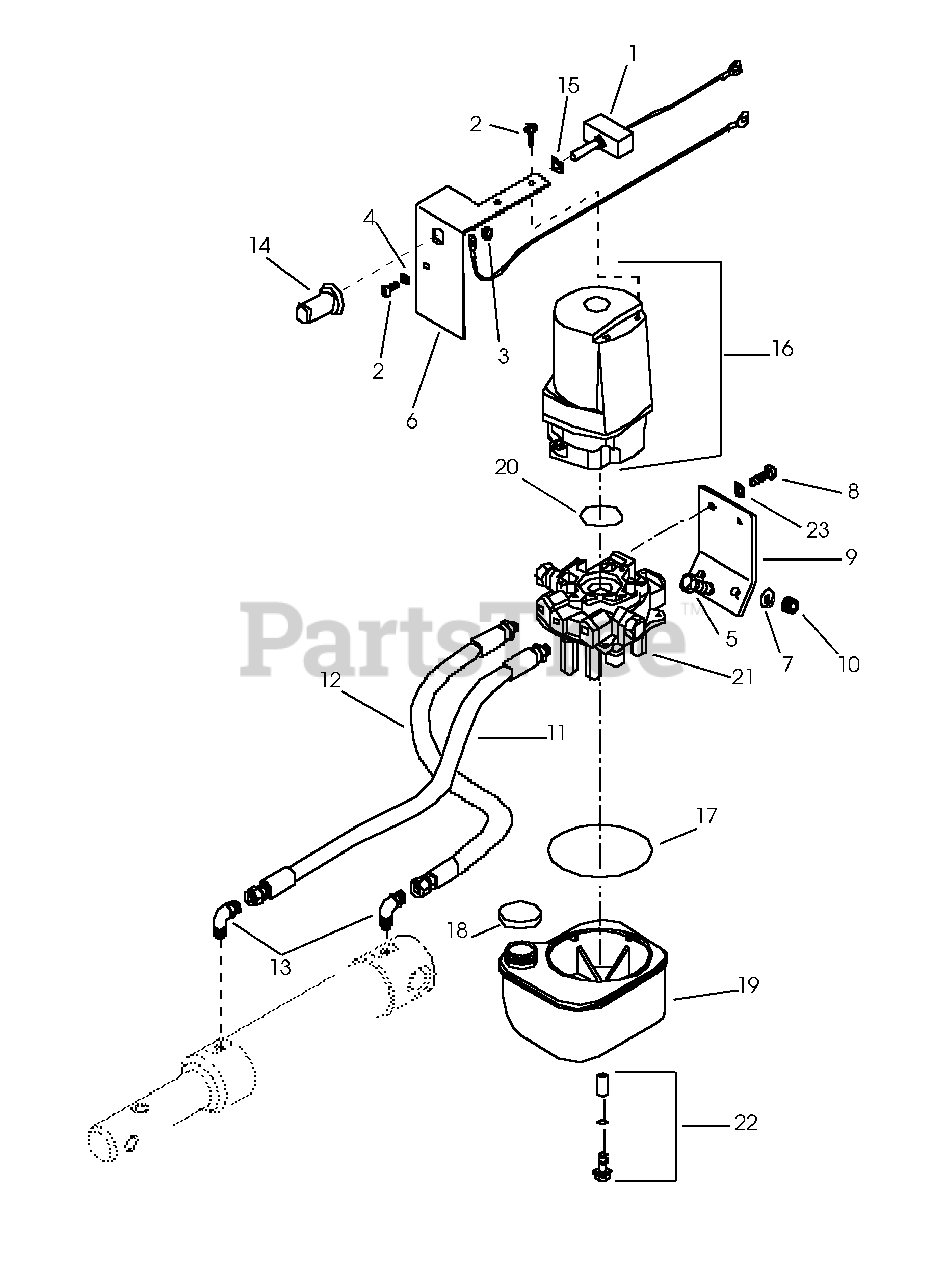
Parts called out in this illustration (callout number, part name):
1	Assembly-Switch
2	Screw-Machine-Hex-Washer-Head 10-24 x .75
3	Nut-Locking-Nylon 10-24
4	Washer-Flat-Steel .281 x .625 x .065
5	Bolt-Hex .38-16 x 1.00 Grade 5
6	Switch Plate
7	Washer-Flat-Steel .406 x .812 x .065
8	Bolt-Hex .375-16 x .75 Grade 5
9	Lift Pump Mounting Bracket
10	Nut-Locking-Center .375-16
11	Assembly-Hose Pump to Cylinder
12	Assembly-Hose Pump to Cylinder
13	Adapter 2503-4-4
14	Boot-Switch
15	Washer-Flat-Steel .505 x .880 x .072
16	Assembly-Motor
17	Reservoir Seal-O-Ring
18	Reservoir-Cap
19	Reservoir-Tank
21	Assembly-Adapter
22	Assembly-Screw-O-Ring and Spacer
23	Washer-Locking .38 x .094
